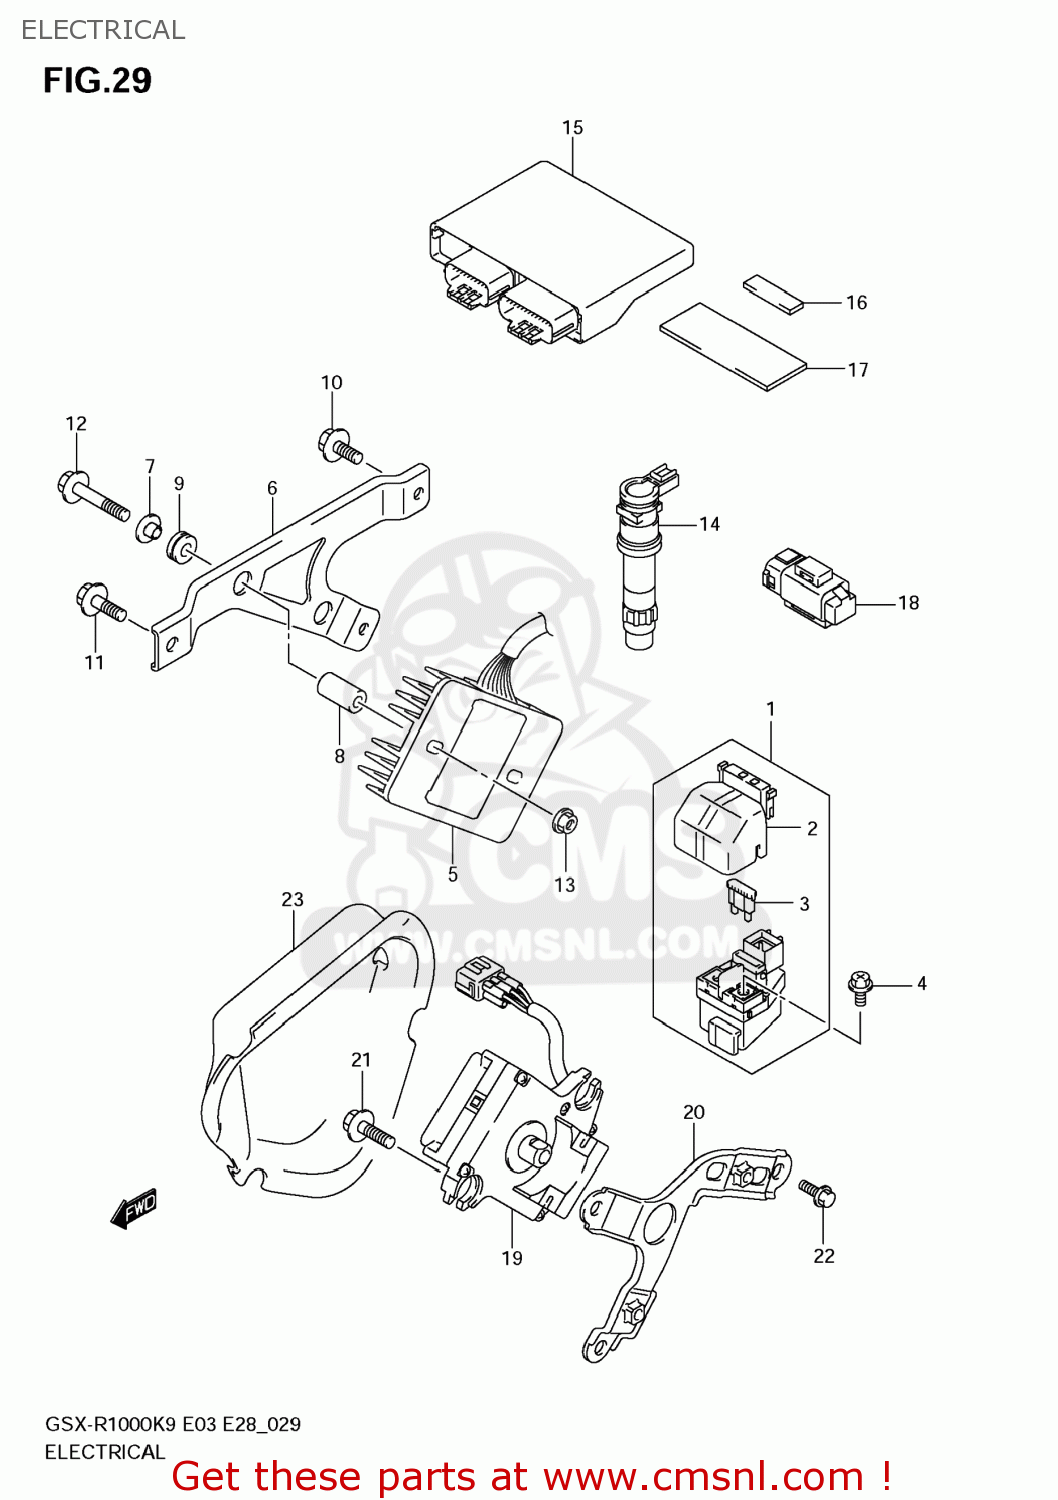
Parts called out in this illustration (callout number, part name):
1	RELAY ASSY,STARTING MOTOR
2	COVER
3	FUSE(30A)
4	SCREW(6X8)
5	RECTIFIER ASSY
6	BRACKET,RECT FTG
7	SPACER(6.2X8.4X6.9)
8	SPACER(6.2X14.5X26)
9	CUSHION
10	BOLT
11	BOLT
12	BOLT
13	NUT
14	COIL ASSY,IGNITION
15	CONTROL UNIT,FI
16	CUSHION,FI CONTROL UNIT
17	PROTECTOR(80X80X2)
18	SENSOR ASSY,FUEL CUT
19	ACTUATOR ASSY,
20	HOLDER,ACTUATOR
21	BOLT(6X25)
22	BOLT
23	COVER,ACTUATOR
